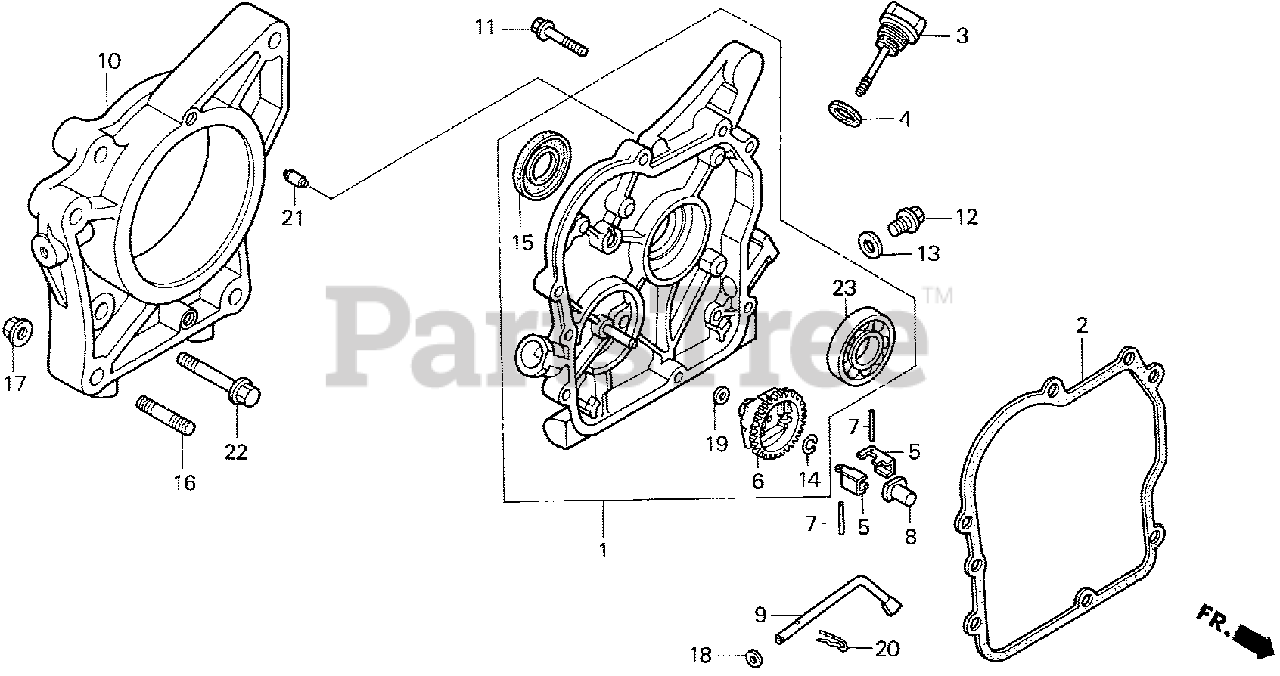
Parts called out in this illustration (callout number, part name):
1	COVER ASSY., CRANKCASE
2	GASKET, CASE COVER
3	CAP, OIL FILLER
4	GASKET, OIL FILLER CAP
5	WEIGHT, GOVERNOR
6	HOLDER, GOVERNOR WEIGHT
7	PIN, GOVERNOR WEIGHT
8	SLIDER, GOVERNOR
9	SHAFT, GOVERNOR ARM
10	HOUSING, RR. CLUTCH
11	BOLT, FLANGE (6X28)
12	BOLT, DRAIN PLUG
13	WASHER, DRAIN PLUG (10.2MM)
14	CLIP, GOVERNOR HOLDER
15	OIL SEAL (17X30X6) (NOK)
16	BOLT 2, STUD (8X32)
17	NUT, FLANGE (8MM)
18	WASHER, PLAIN (5MM)
19	WASHER, PLAIN (6MM)
20	PIN, LOCK (8MM)
21	PIN, DOWEL (6X10)
22	BOLT, FLANGE (8X38)
23	BEARING, RADIAL BALL (6203)
